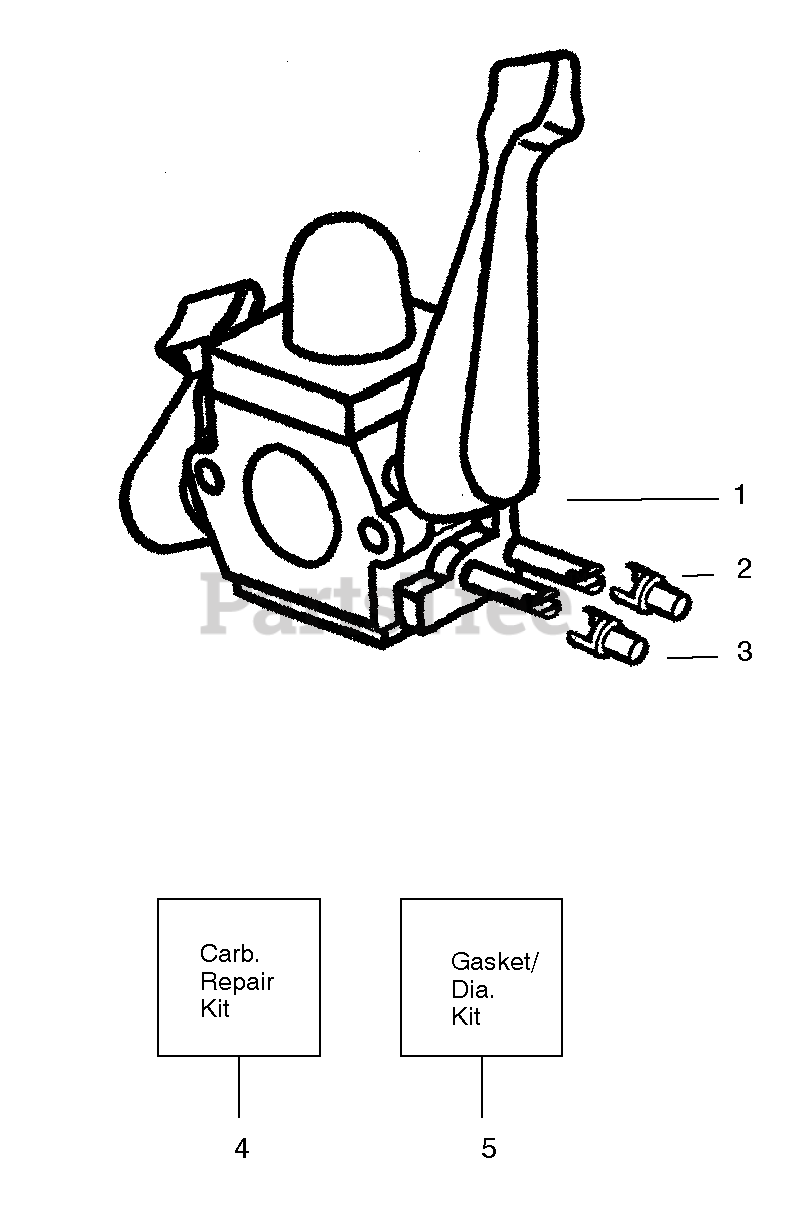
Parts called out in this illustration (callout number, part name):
1	Assy-Carb. Zama (C1Q-W11)
2	Cap-Limiter (high) brown
3	Cap-Limiter (low) tan
4	Kit-Carb. Repair
5	Kit-Carb. Gasket (Zama)
